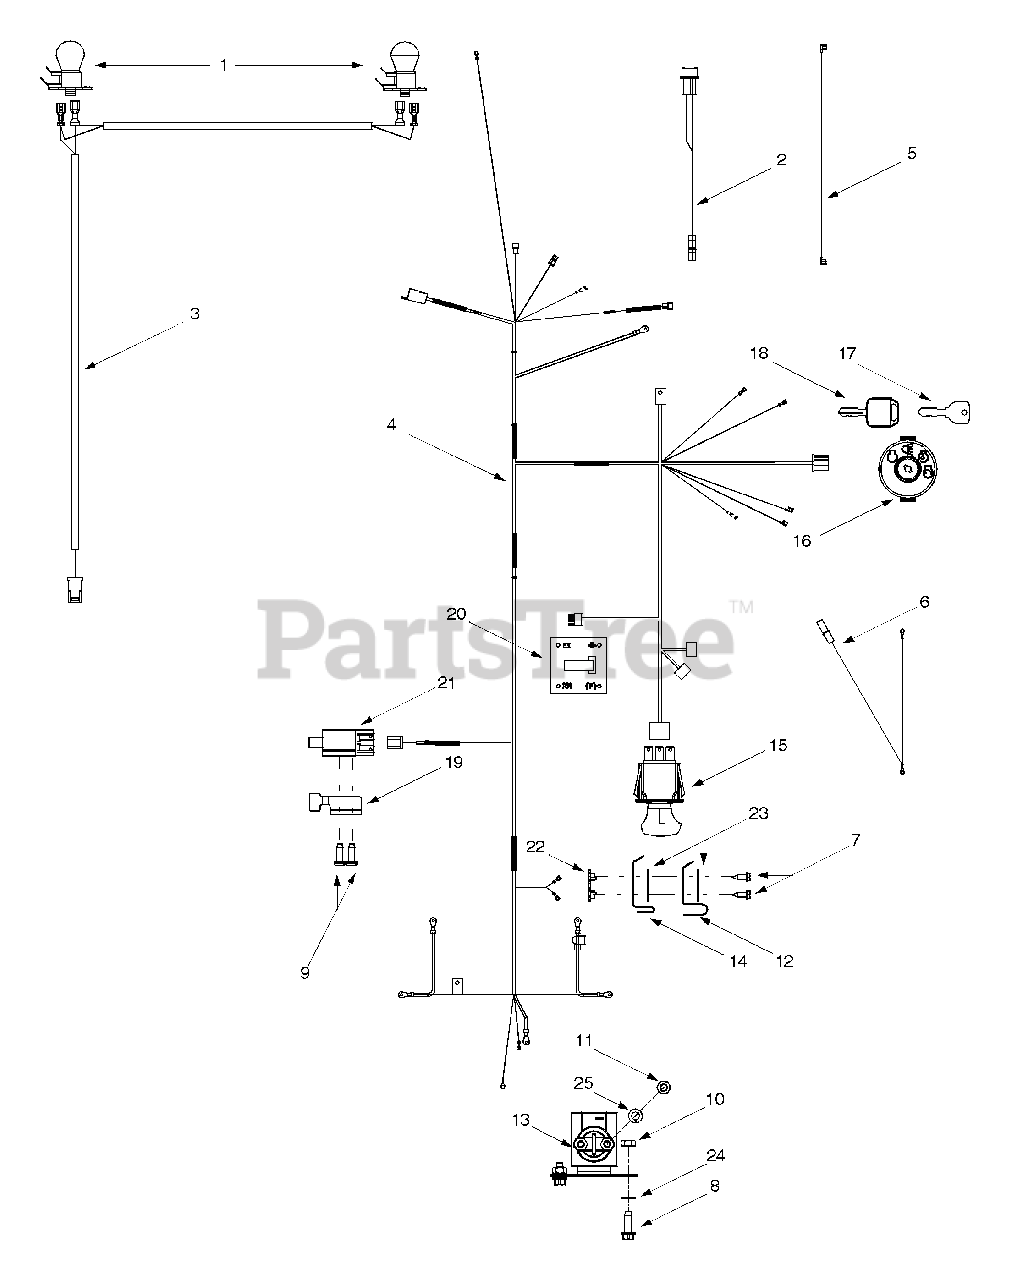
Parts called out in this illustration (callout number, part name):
1	Bulb/Socket Headlight Assembly
2	Wire Harness, Afterfire Solenoid, #18 x 5
3	Wire Harness, Headlight
4	Wire Harness, Main
5	Wire Assembly, Reverse Jumper
6	Wire Assembly, Ground Jumper
7	Self-tapping Screw, #8-18 x .5
8	Self-tapping Screw, 1/4-20 x .75
9	Pan Phillips Screw, #12-16 x .625
10	Hex Sems Nut, 1/4-20
11	HEX NUT
12	Outer Seat Spring Switch
13	12V Solenoid, 100 Amp
14	Inner Seat Spring Switch
15	Electric PTO Switch
16	Ignition Switch
17	Ignition Key
18	Ignition Key w/ Plastic Cover
19	Parking Brake Switch Spring
20	Systems Indicator Monitor, Hour Meter
21	Plunger Switch (Parking Brake)
22	Insulator Boss Plate
23	Insulator Plate
24	External Lock Washer, 1/4
25	Lock Washer, 1/4
